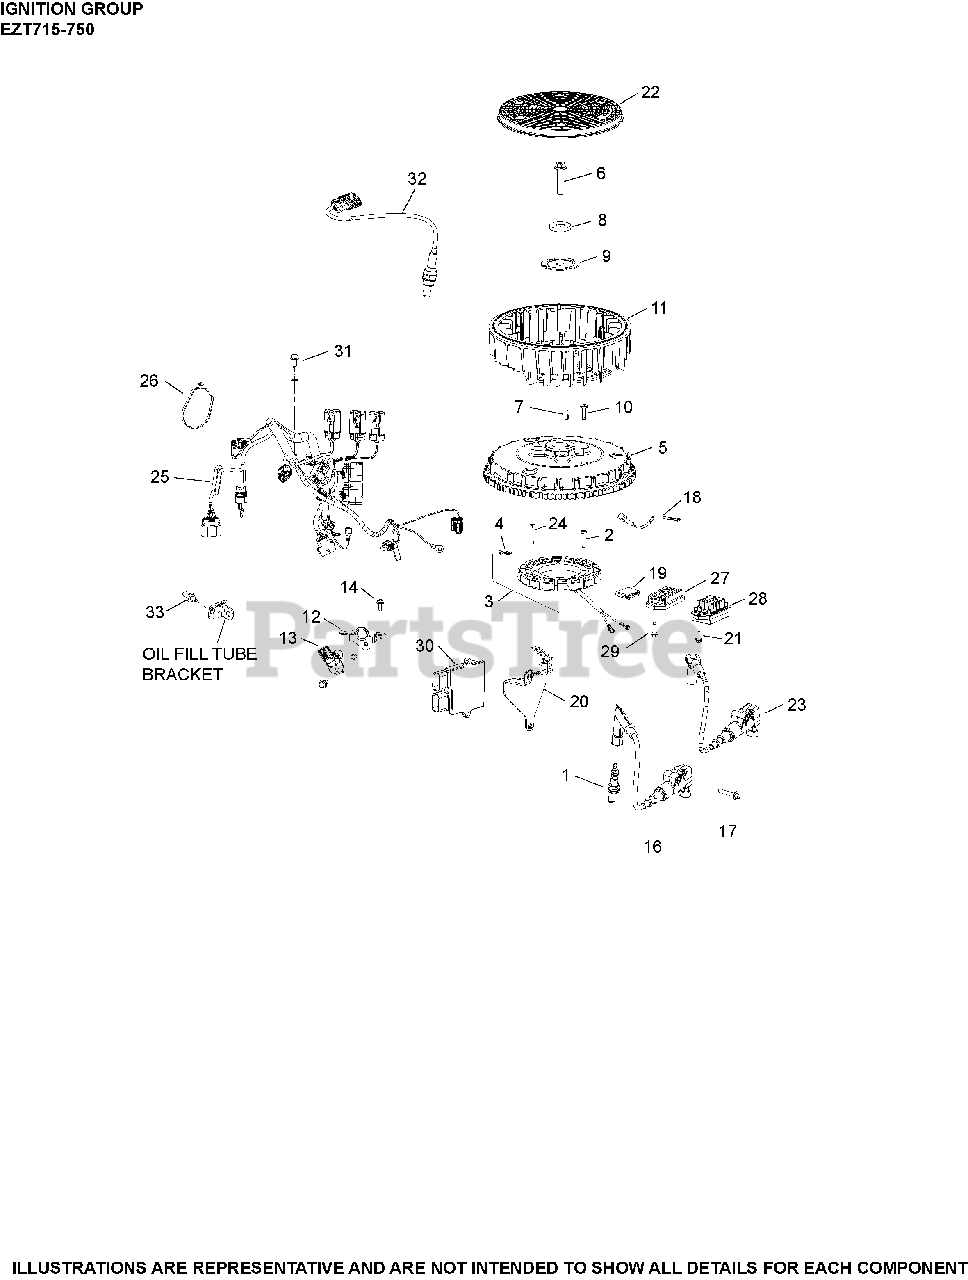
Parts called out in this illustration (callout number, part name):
1	PLUG, SPARK
2	SCREW, THREAD FORMING
3	KIT, 15 / 20 AMP STATOR
5	FLYWHEEL , ASSEMBLY
6	SCREW, HEX FLANGE
7	KEY, SQUARE
8	WASHER, FLAT
10	RETAINER, FLYWHEEL FAN
12	BRACKET, SENSOR
13	SENSOR, SPEED
14	SCREW, FLG THD FRM M5X0.8X13
17	SCREW, FLG M6X1.0X34
18	LEAD , REGULATOR RECTIFIER JUMPER
19	CONNECTOR
20	BRACKET , ECU
21	SCREW, THREAD FORMING
23	COIL, IGNITION - EFI
25	HARNESS, W/TEMP SENSOR
28	REGULATOR, RECTIFIER (20/25 AMP) USE 25 403 32-S
30	MODULE, ECU
31	SCREW, CAPTIVE WASHER (SEMS)
